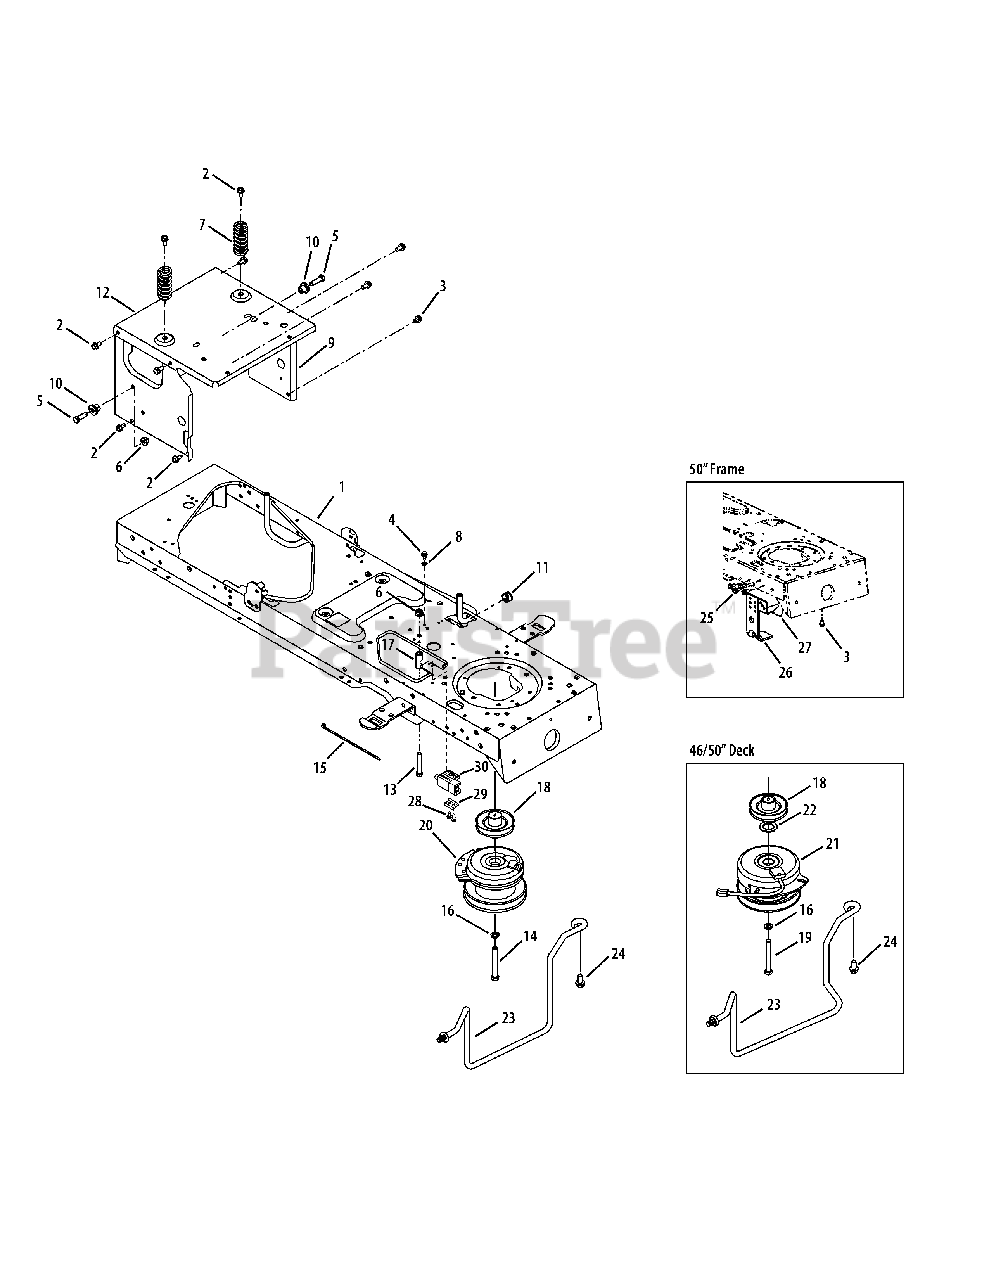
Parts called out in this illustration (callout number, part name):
3	Screw, Hex Wash. Tapp, 5/16-18 x .5
4	Screw, Hex Wash. Hd. Tapp, 1/4-20 x 0.625
5	Hex Screw 3/8-16 x 1.25
6	Nut, Nylon Lock, 3/8-16
7	Spring, Compression, 1.28 OD x 3.125
8	Washer, Lock, Ext. 1/4
11	Snap Bushing
13	Screw, 3/8-16 x 2.25 GR5
14	Screw, Hex Cap, 7/16-20 x 3.25 GR5
15	Cable, Tie, 3/16 x .05 x 7.4
16	Washer, Lock, 7/16, Regular Duty
17	Spacer, 3/8 x 1.54
18	Electric PTO Engine Pulley
19	Screw, Hex Cap , 7/16-20 x 3.5 GR5
20	Clutch, PTO
21	Clutch, PTO
22	Washer, Flat, 1.031 x 1.62 x .095
23	Rod, Belt Keeper
24	Screw, 5/16-18, .75
25	Screw, 5/16-12, 0.75
28	Screw, #10 - 16, x .500
29	Switch Mounting Plate
30	Interlock Switch
